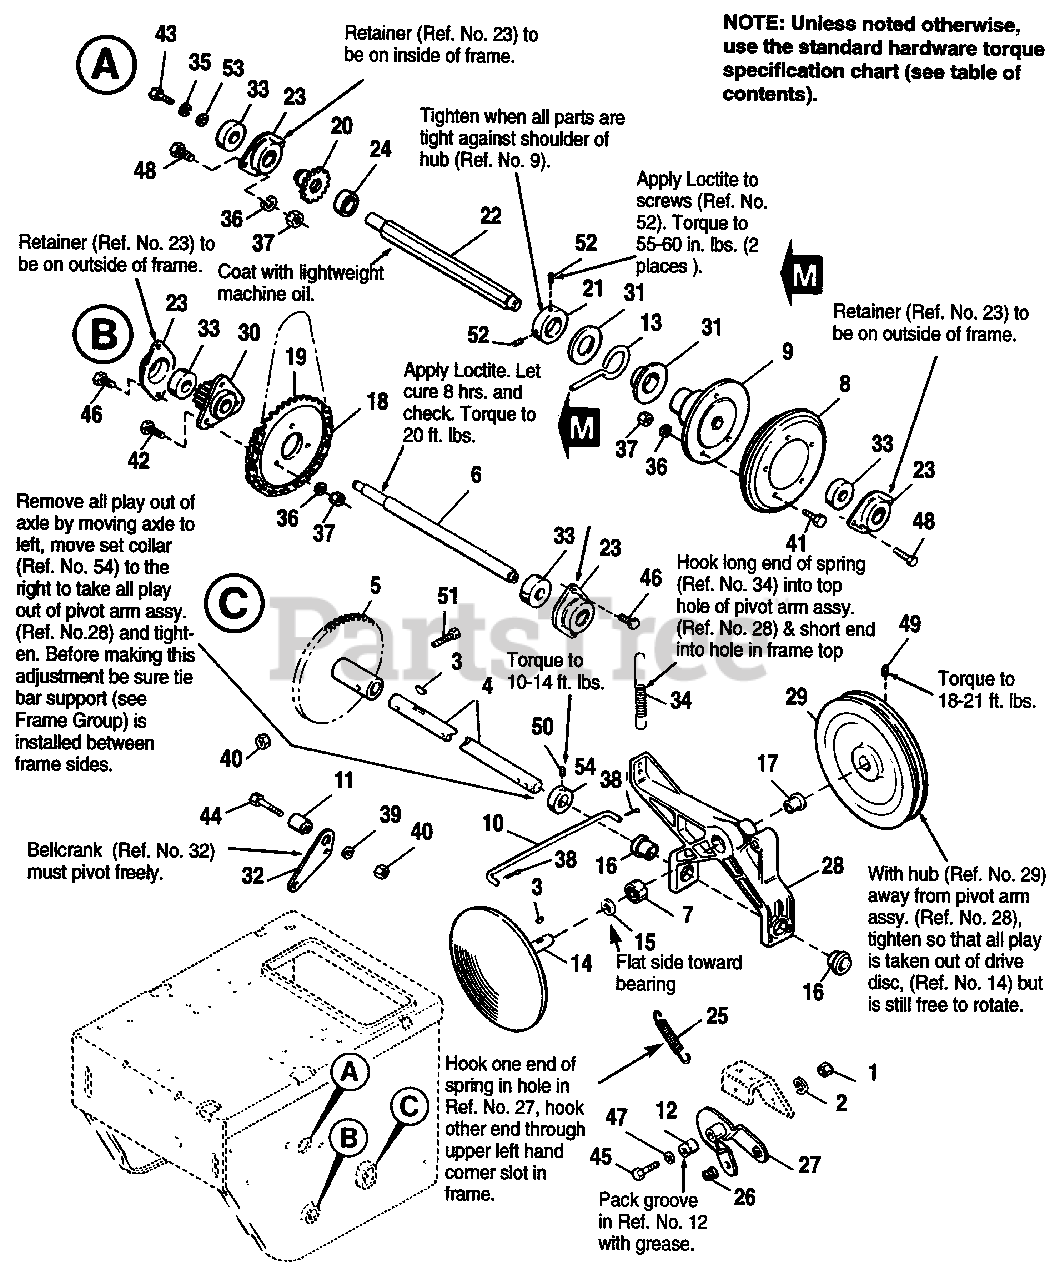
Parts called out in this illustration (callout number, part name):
1	NUT, Hex, 3/8-16
2	LOCKWASHER, 3/8
3	KEY, Woodruff, 3/16 x 5/8
8	DISC, Friction
9	HUB, Friction Disc
11	BUSHING, Pivot
12	BUSHING, Spacer
14	DISC, Drive
18	CHAIN, Drive
19	SPROCKET, 36 Tooth
20	SPROCKET, 10 Tooth
23	RETAINER, Bearing
25	SPRING
26	BUSHING, Ball
27	ARM ASSY., Shift w/Bushings (Includes Ref. No. 26)
28	ARM ASSY., Pivot w/Bushings
29	PULLEY, Traction
30	GEAR & BEARING ASSY., 10 Tooth
31	COLLAR, Thrust
35	LOCKWASHER, 1/4
36	LOCKWASHER, 5/16
37	NUT, Hex, 5/16-18
38	PIN, Cotter, 1/8 x 3/4
39	WASHER, Flat, 11/32
40	NUT, Hex, Lock, 5/16-18
41	CAPSCREW, Hex Hd., 5/16-18 x 3/4
42	CAPSCREW, Hex Hd., 5/16-18 x 1
43	CAPSCREW, Hex Hd., 1/4-20 x 5/8
44	CAPSCREW, Hex Hd., 5/16-18 x 1-3/4
45	CAPSCREW, Hex Hd., 3/8-16 x 2
46	SCREW, Taptite, 5/16-18 x 1/2
47	WASHERS, Flat, 13/32
48	CAPSCREW, Hex Hd., 5/16-18 x 5/8
49	SETSCREW, Sq. Hd., 5/16-18 x 1/2
50	SETSCREW, Sq. Hd., 5/16-18 x 1/2
51	CAPSCREW, Hex Hd., 5/16-18 x 1-1/2
52	SETSCREW, Socket Hd., 1/4-20 x 3/8
53	WASHER, Flat, 1/4
54	SET COLLAR
